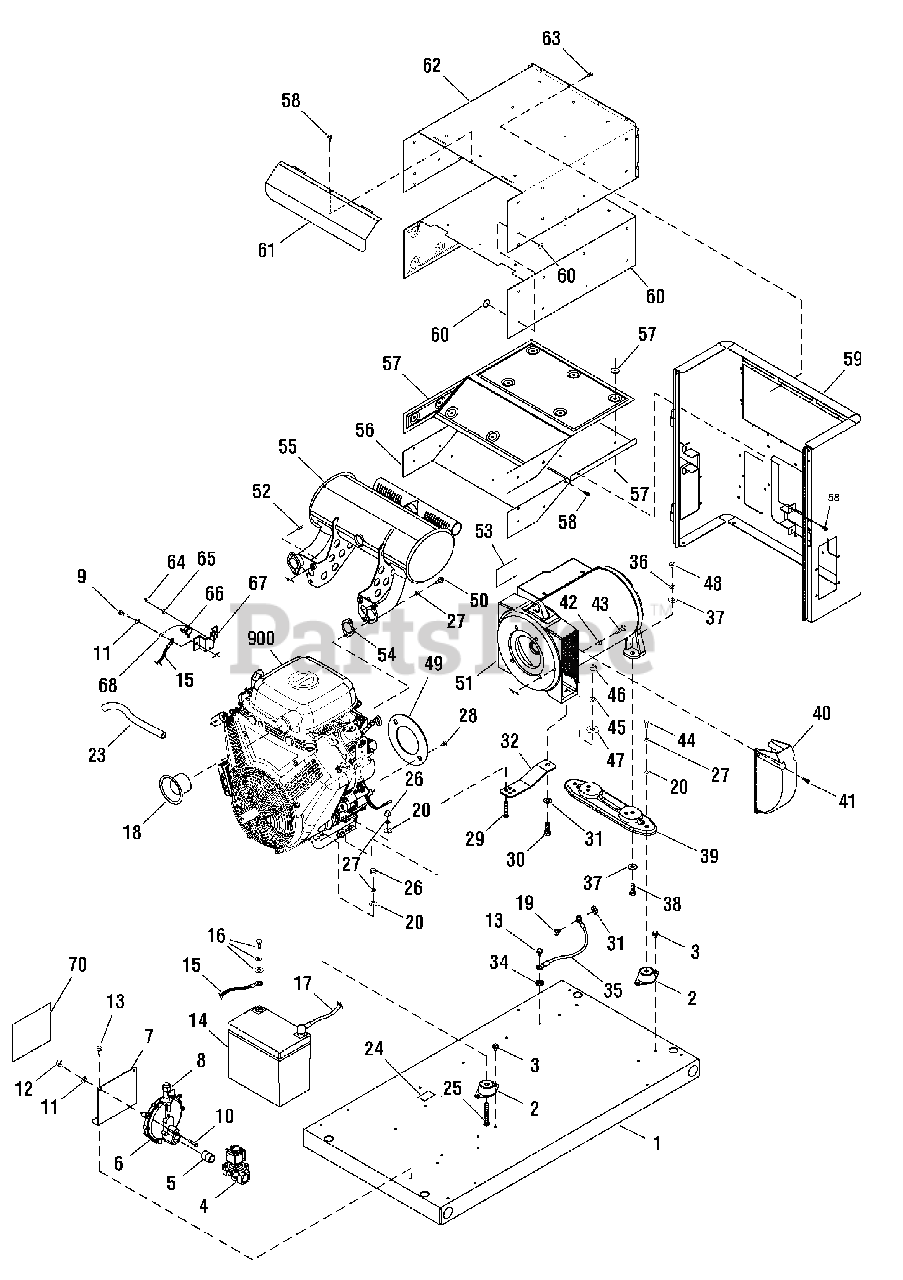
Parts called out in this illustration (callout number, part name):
1	BASE, Mounting
2	MOUNT, Vibration
3	CAPSCREW, Hex Head, Trilobular, 5/16- 8 x 1/2
4	SOLENOID, Gas Fuel
5	FITTING, Coupling
6	REGULATOR, NG/LPG
7	BRACKET, Mounting Solenoid
9	*CAPSCREW, Hex Head, M6-1 x 16
10	*CAPSCREW, Hex Head, M6-1 x 30
11	*WASHER, Lock, 1/4
12	*NUT, M6-1
13	SCREW, Hex Head, Trilobular, 1/4-20 x 1/2
16	KIT, Harware, Battery
18	TUBE, Air Cleaner
19	*CAPSCREW, Hex Head, M6-1 x 12
20	*WASHER, Flat, 5/16-M8
23	HOSE, Oil Drain
24	DECAL, Oil Drain
25	*CAPSCREW, Hex Head, Full Thread, 5/16 - 18 x 2-1/2
26	*NUT, 5/16-18
27	*WASHER, Lock, 5/16-M8
28	*CAPSCREW, Hex Head, Sems, 5/16-24 x 3/4
29	*CAPSCREW, Hex Head, 5/16-18 x 2
30	*CAPSCREW, Hex Head, M12-1-3/4 x 35
31	*WASHER, M12
32	SUPPORT, Engine/Alternator
34	*WASHER, Shakeproof, Ext. M6-1/4
36	*WASHER, Lock, M10
37	*WASHER, Flat, M10
38	*CAPSCREW, Hex Head, M10-1-1/2 x 30
39	BRACKET, Mounting Alternator
41	*SCREW, Phillips Head, M5-0.8 x 20
42	*WASHER, Lock, 3/8
43	*CAPSCREW, Hex Head, 3/8-16 x 1-1/4
44	*CAPSCREW, Hex HEad, 5/16-18 x 3/4
45	*WASHER, Lock, M12
46	*NUT, Hex, M12 - 1-3/4
47	*WASHER, Flat, M12
48	*NUT, M10 - 1.5
49	DISK, Engine Air
50	SCREW
51	ALTERNATOR
53	DECAL, Caution Hot Surface
56	BASE, Muffler Box
57	KIT, Insulation, Muffler Base
58	CRIMPTITE, 10 - 24 x 1/2
59	ASSEMBLY, Bulkhead, Alternator End w/Insulation
60	KIT, Insulation, Muffler Box
61	COLLECTOR, Muffler Box
62	BOX, Muffler Top
63	SCREW, 10-32 x 5/8
64	*SCREW, Phillips Head, 4-40 x 0.19
65	*WASHER, Lock, #4
66	SWITCH, Oil Temp
67	PLATE, Switch Oil Temp
70	DECAL, Requirements, Fuel
900	** ENGINE
